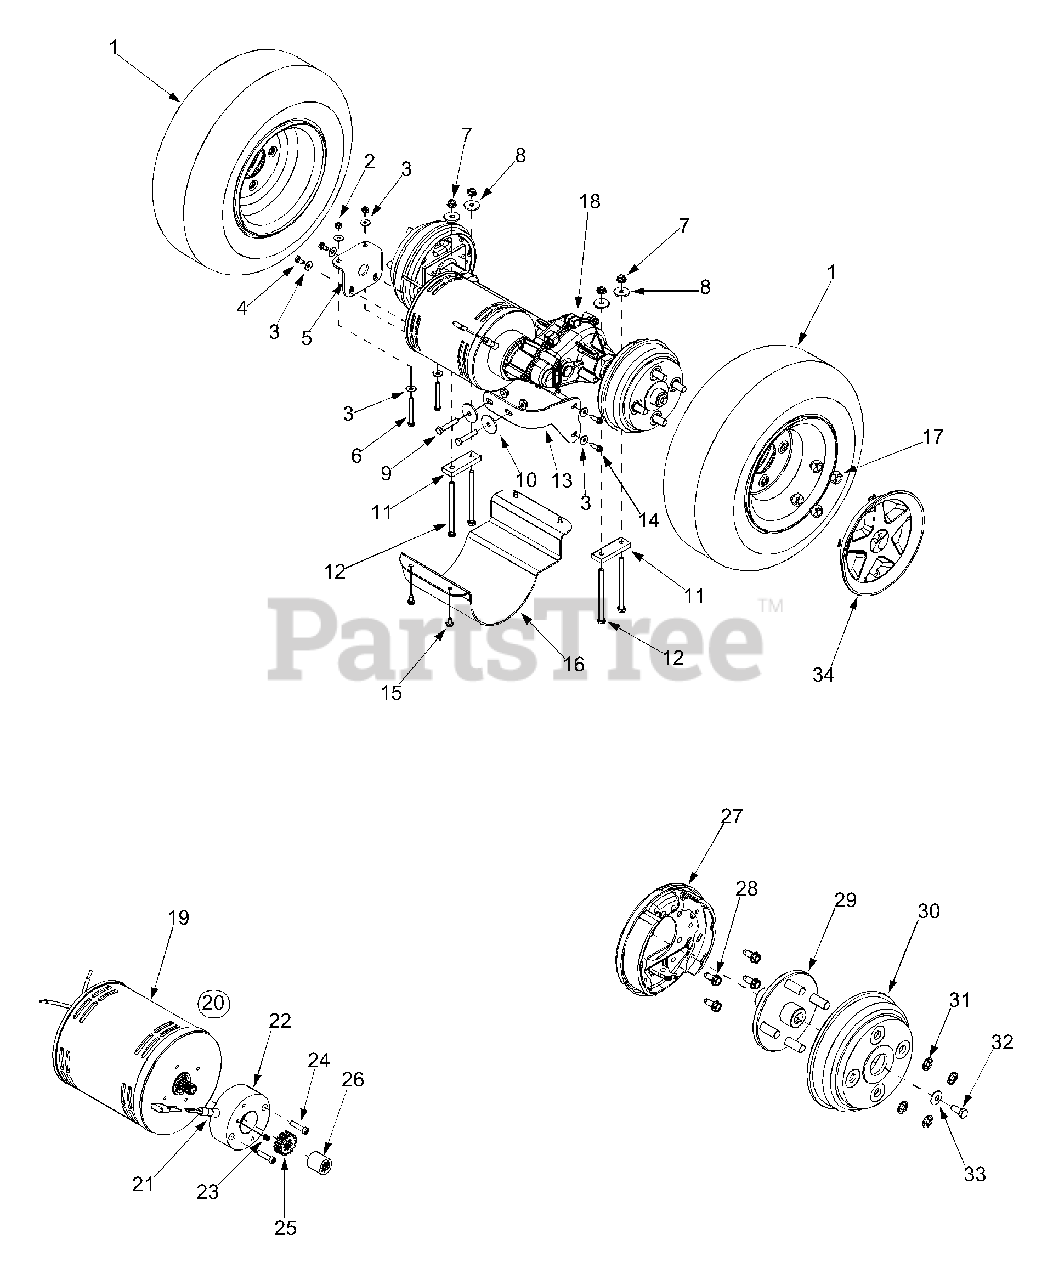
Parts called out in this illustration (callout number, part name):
1	Rear Wheel Assembly
2	Hex Nut 1/4-20
3	Flat Washer .265 ID x .750 OD
4	Hex Cap Screw 1/4-20 x .750
5	Motor Support Bracket
6	Hex Cap Screw 1/4-20 x 2.25
7	Flange Lock Nut 5/16-18
8	Flat Washer .344 ID x 1.25 OD
9	Hex Cap Screw 5/16-18 x 1.75
10	Flat Washer .344 ID x 1.5 OD
11	Transmission Mounting Strap
12	Hex Cap Screw 5/16-18 x 4.50
13	Transmission Torque Bracket
14	Hex Washer Screw 1/4-20 x .750
15	Hex Washer Screw 1/4-20 x .500
16	Motor Shield
18	Transmission Assembly
19	48V Electric Motor
20	Motor Speed Sensor Assembly
21	RPM Sensor
22	Motor Spacer
23	Set Screw 1/4-20 x .38
24	Screw 1/4-20
26	Motor Spline Coupling
27	Brake Shoe Assembly - RH
28	Hex Washer Screw 5/16-18 x .750
29	Hub Stud Assembly
30	Brake Drum
31	Nut Spacer .50
32	Hex Cap Screw 5/16-24 x .750
33	Bell Washer .340 ID x .872 OD
34	Hubcap
